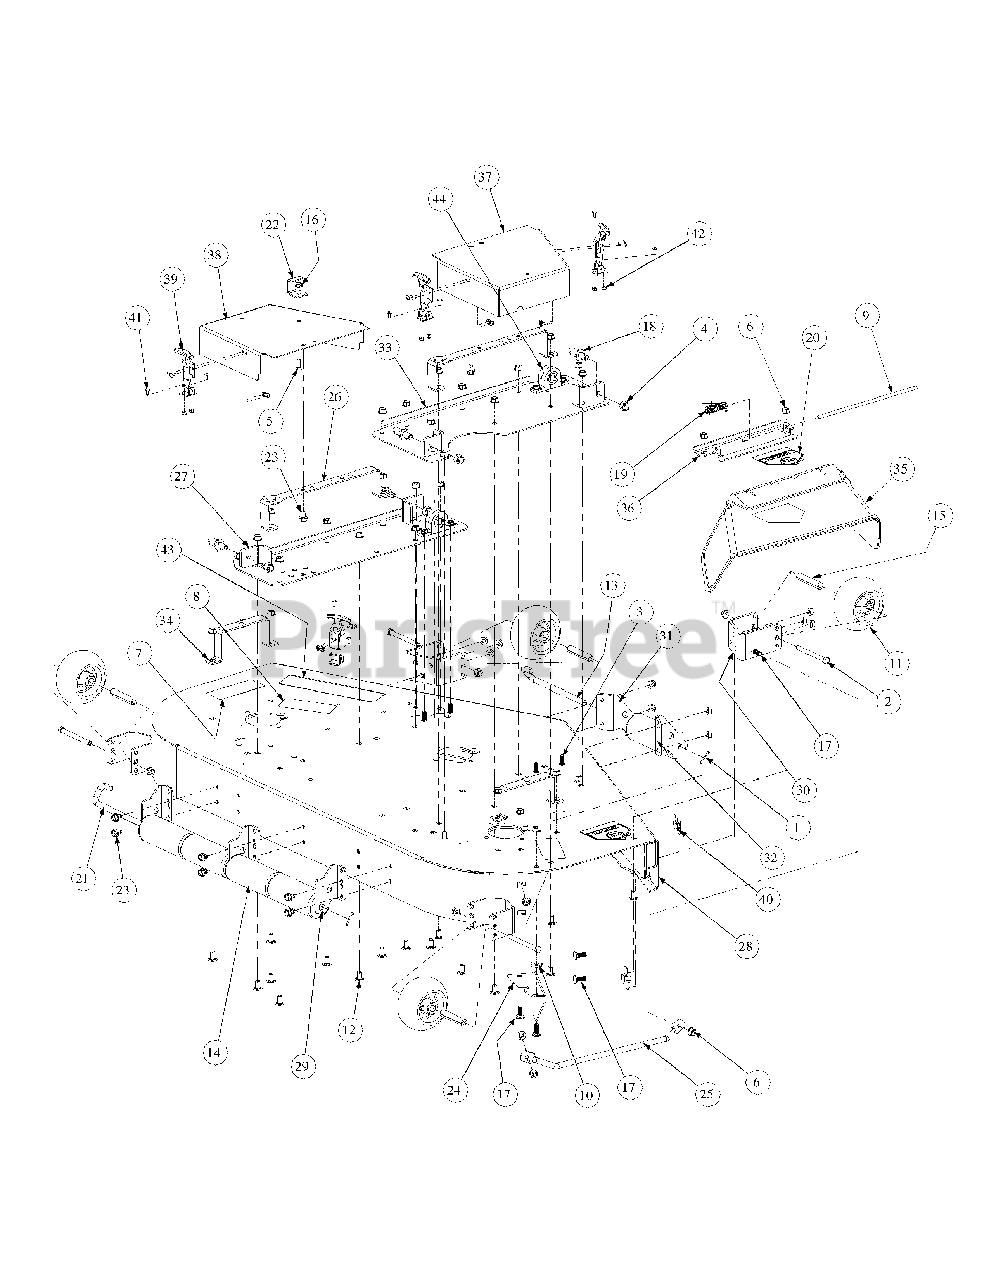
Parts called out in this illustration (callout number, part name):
1	Cotter Pin, .125 Dia x 1.0
2	Hex Cap Screw, 3/8-16, 3.75
3	Carriage Screw, 3/8-16 x 1.25
4	Lock Nut, Nylon Insert, 1/2-13
5	Hex Cap Screw, 5/16-18 x 3/4
6	Hex Nut, 3/8-16 Flange Lock
7	Decal Rotating Blade
8	Decal, Warning Shield Missing
9	Deflector Chute Rod
10	Idler Washer
11	Complete Wheel, 5.00 Dia.
12	Carriage Bolt, 3/8-16 x .75 Lg.
13	Roller Pin. 1/2 Dia. x 7.31 Lg.
14	Front Roller
15	Wheel Spacer
16	Hexflange Lock Nut, 5/16-18
17	Carriage Bolt, 3/8-16 x 1
18	Pin, 5/8 Dia. x 1.2 Lg.
19	Spring Torsion, 0.4 ID x 2.16 LG
20	Decal, Danger Hands and Feet
21	Roller Pin
22	Tension Rod Stop Bracket
23	Hex Index Washer Screw, 3/8-16, .5
24	Chute Bracket
25	Finger Guard
26	Cover Support
27	Left Hand Mount, Deck Bracket Assembly
28	54 Deck Assembly
29	Roller Mount Bracket
30	Anti-Scalp Wheel, Front Mount Bracket
33	Deck Bracket Assembly
34	Outer Belt Cover Support Assembly
35	Deflector Chute
36	Deflector Chute Bracket
37	Right Hand Belt Deck Cover
38	Left Hand Belt Deck Cover
39	T-Handle Draw Latch
40	Decal, 54"
41	Phillips Head Screw, 10-32
42	Lock Nut, Nylon Insert, 10-32
43	Mower Deck Label
44	Pillow Block
